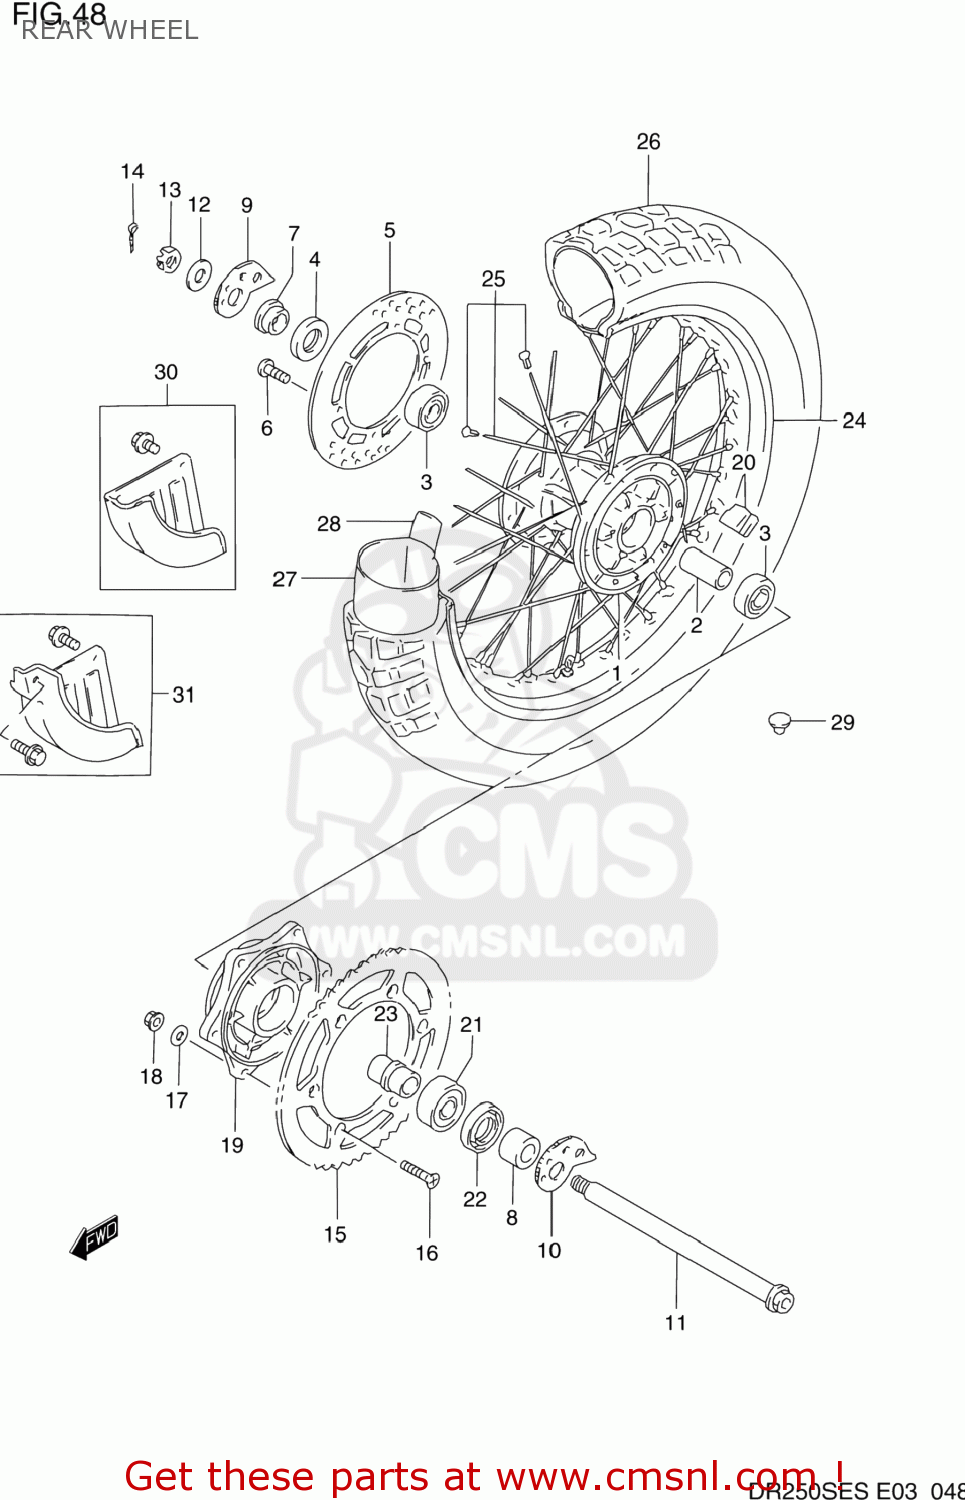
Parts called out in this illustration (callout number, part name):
1	HUB,RR WHEEL
2	SPACER,RR HUB BEARING
3	BEARING
4	SEAL,OIL(26X47X5)
5	DISC,RR BRAKE
6	BOLT
7	SPACER,RR AXLE,R
8	SPACER,RR AXLE,L
9	ADJUSTER,CHAIN
10	ADJUSTER,CHAIN,L
11	AXLE,RR
12	WASHER(19X32X3.2)
13	NUT
14	PIN,COTTER
15	SPROCKET,RR(NT:49)
16	BOLT(8X30.5)
17	WASHER
18	NUT
19	DRUM,REAR SPROCKET MOUNT
20	ABSORBER,RR HUB SHOCK
21	BEARING(25X52X15)
22	SEAL,OIL(34X52X6)
23	RETAINER,RR SPROCKET DRUM
24	RIM,REAR WHEEL (18X2.15)
25	SPOKE SET,RR WHEEL
26	TIRE
27	TUBE ASSEMBLY,WHEEL,INNER
28	PROTECTOR,WHL INR TUBE
29	CAP(OD:12)
30	COVER SET,REAR BRAKE DRUM
31	COVER SET,RR BRAKE DISC
